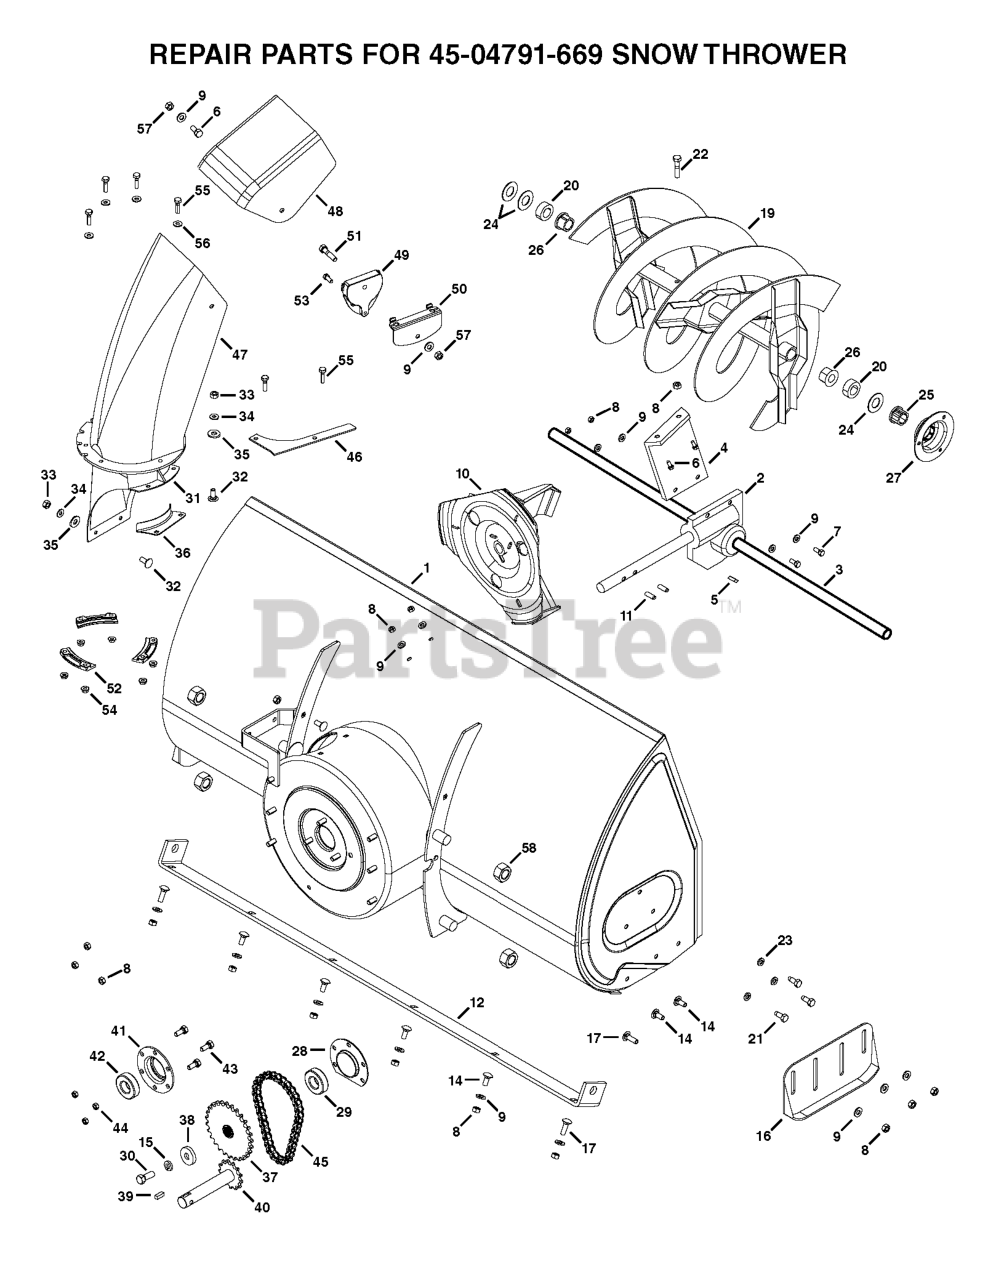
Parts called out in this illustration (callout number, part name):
2	GEAR BOX 71464
6	HEX BOLT 5/16ÄX3/4Ä
14	CARRIAGE BOLT
15	LOCK WASHER
23	LOCK WASHER
29	BALL BEARING
49	CABLE GUIDE
55	BOLT
